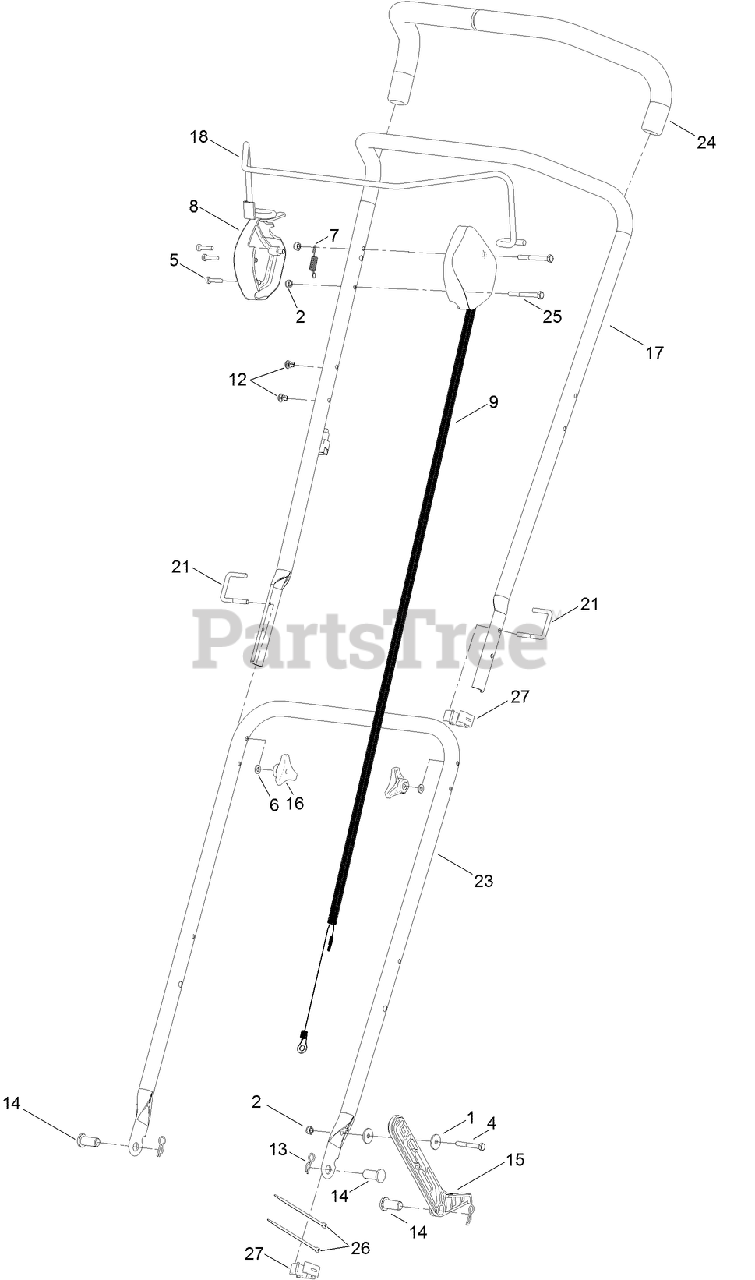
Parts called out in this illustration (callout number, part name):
1	WASHER
2	NUT-NYLOC
4	BOLT-HH
5	SCREW-PLASTITE
7	SPRING-RETURN
8	BOX-SWITCH, LH
9	OPC WIRE LOOM ASM
12	FASTENER-DRIVE
13	CLIP-R
14	PIN-RETAINING
15	FOOTSTOP
16	HANDWHEEL
17	HANDLE-UPPER
18	ARM-BAIL
21	BOLT-U
23	HANDLE-LOWER
24	GRIP-HANDLE
25	BOLT-HEX
26	TIE-CABLE
27	GUIDE-CABLE
